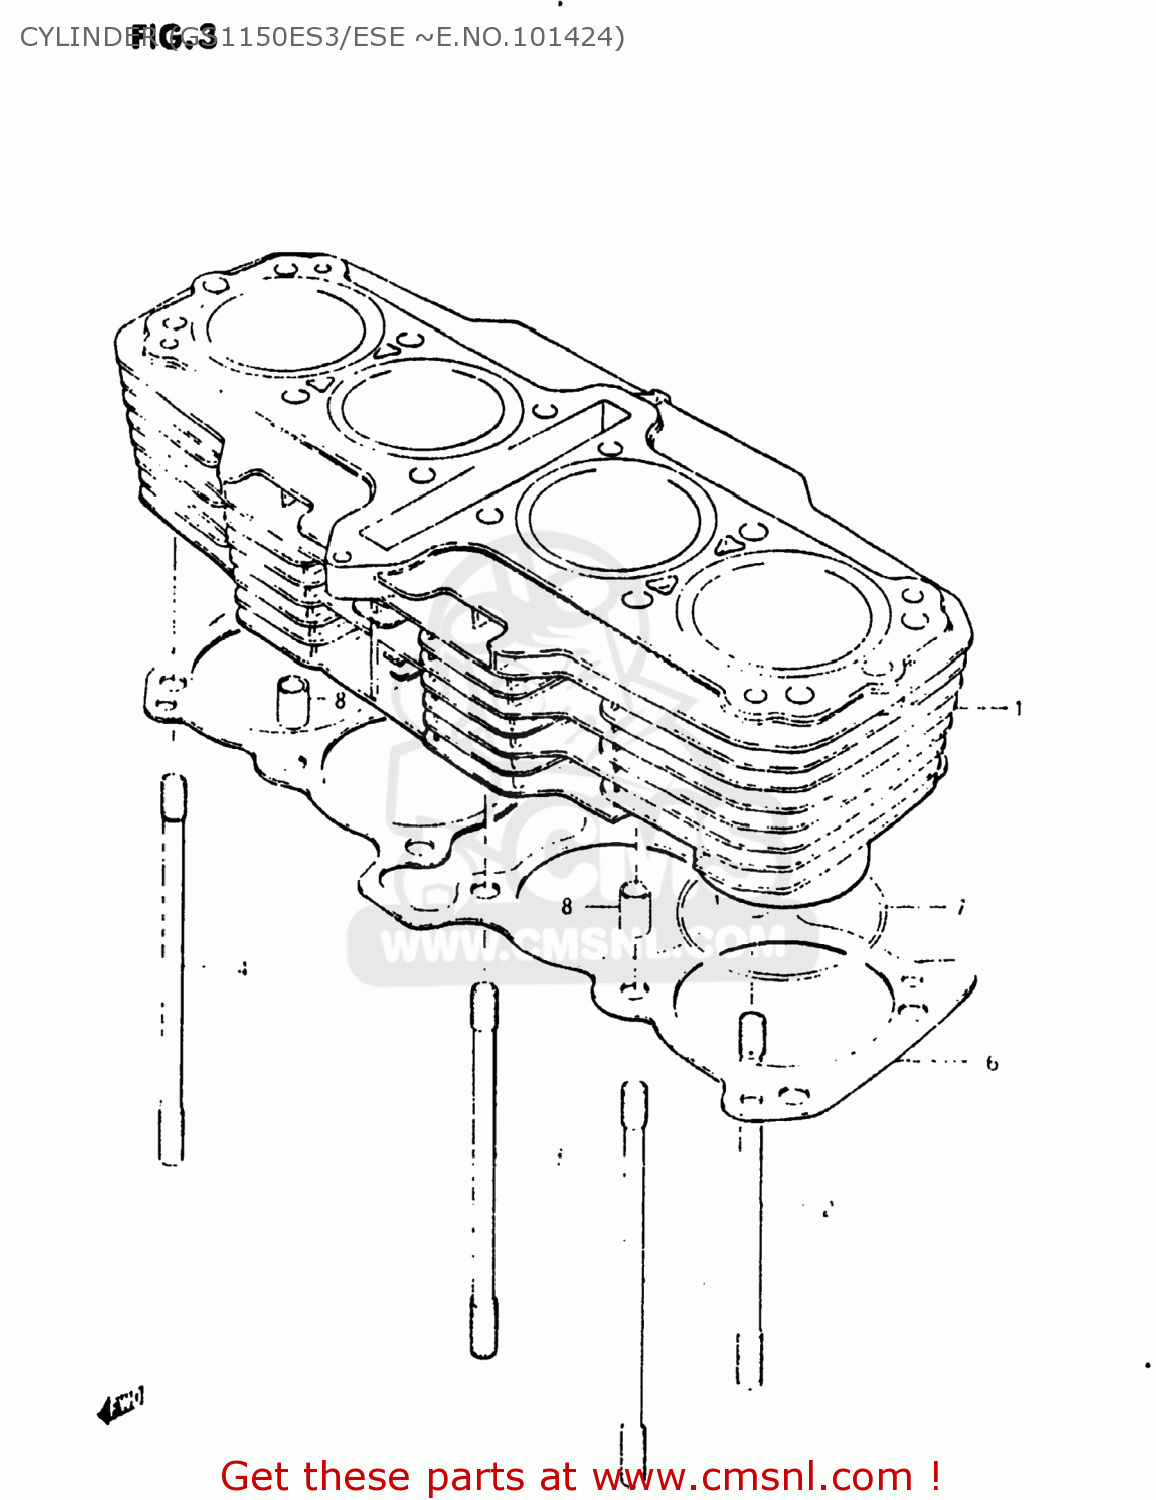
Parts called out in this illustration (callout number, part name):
1	CYLINDER
2	BOLT,STUD
3	STUD
4	STUD
5	BOLT,STUD
6	GASKET,CYLINDER HEAD (NAS)
7	O RING(D:2,ID:77)
8	PIN
